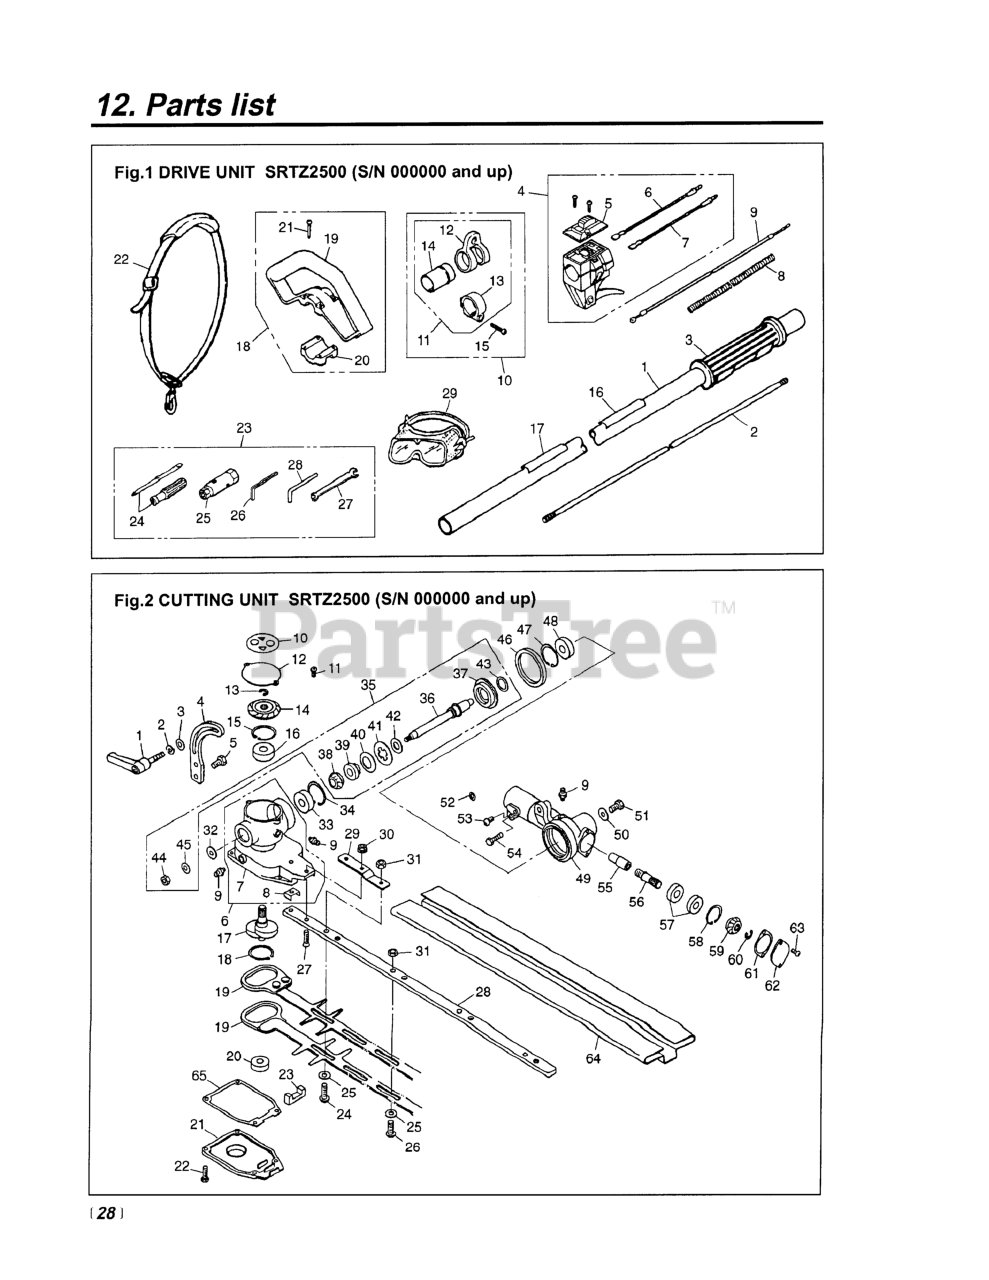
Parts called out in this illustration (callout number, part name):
1-1	PIPE COMPLETE
1-2	SHAFT
1-3	GRIP (RPLS 3577-32140 & 3220-
1-6	CORD (A), BLACK
1-7	CORD (B), RED
1-8	TUBE (RPLS 4900-72141)
1-9	CABLE (RPLS 5580-83100)
1-10	HANGER ASSEMBLY
1-11	HANGER COMPLETE
1-12	HANGER
1-13	CLAMP
1-14	SLEEVE
1-15	SCREW, M5 x 25
1-16	NAMEPLATE
1-17	LABEL (CAUTION)
1-18	HANDLE ASSEMBLY
1-19	HANDLE
1-21	SCREW, M5 x 35
1-22	STRAP ASSY.
1-24	SCREWDRIVER
1-25	SOCKET
1-26	WRENCH (TOOL)
1-27	SPANNER, 8 X 10 (RPLS 2540- )
1-28	BAR
1-29	GOGGLE
2-2	WASHER, M6 X 15
2-3	WASHER, 6 X 6 X 2.0
2-4	PLATE (RPLS-13140)
2-6	CASING (RPLS -13210)
2-7	CASING A
2-8	PLATE
2-9	FITTING, GREASE
2-10	LABEL
2-11	SCREW, M4 X 8
2-13	RING, SNAP
2-14	GEAR, BEVEL
2-15	RING, SNAP, M26 X 1.2
2-16	BEARING
2-17	CRANKSHAFT
2-18	RING, SNAP, M28 X 1.5
2-19	BLADE, SRT, 24
2-20	BEARING
2-21	COVER
2-22	BOLT (RPLS 6782-13450)
2-23	FELT
2-25	WASHER (RPLS 3873-11760)
2-26	SCREW
2-27	SCREW, M5 X 20
2-28	PLATE, GUIDE
2-29	PLATE (RPLS 6780- )
2-30	NUT, M5
2-31	NUT, M6
2-32	WASHER, 6X15X2.0
2-33	BEARING
2-34	RING, SNAP, M22 x 1.2
2-35	KIT, SHAFT (RPLS 6782-13610)
2-36	SHAFT
2-37	GEAR (B)
2-38	GEAR (C)
2-39	BOSS
2-40	WASHER, SPRING
2-41	PLATE
2-42	WASHER
2-43	WASHER
2-44	NUT, M6 X 5
2-45	WASHER, M6 X 15
2-46	O-RING
2-47	RING, SNAP, M26 X 1.2
2-48	BEARING
2-49	CASE- B
2-50	WASHER, 6 X 6 X 2.0
2-52	WASHER
2-53	BOLT, M5 X 10
2-54	BOLT
2-55	JOINT (REPLACES T3078-13810)
2-56	SHAFT, GEAR
2-57	BEARING
2-58	RING, SNAP, M22 x 1.2
2-59	GEAR, BEVEL
2-60	RING, SNAP
2-61	PACKING
2-62	COVER, STOPPER KIT
2-63	SCREW, M4 X 8
2-64	COVER, BLADE
2-65	GASKET
